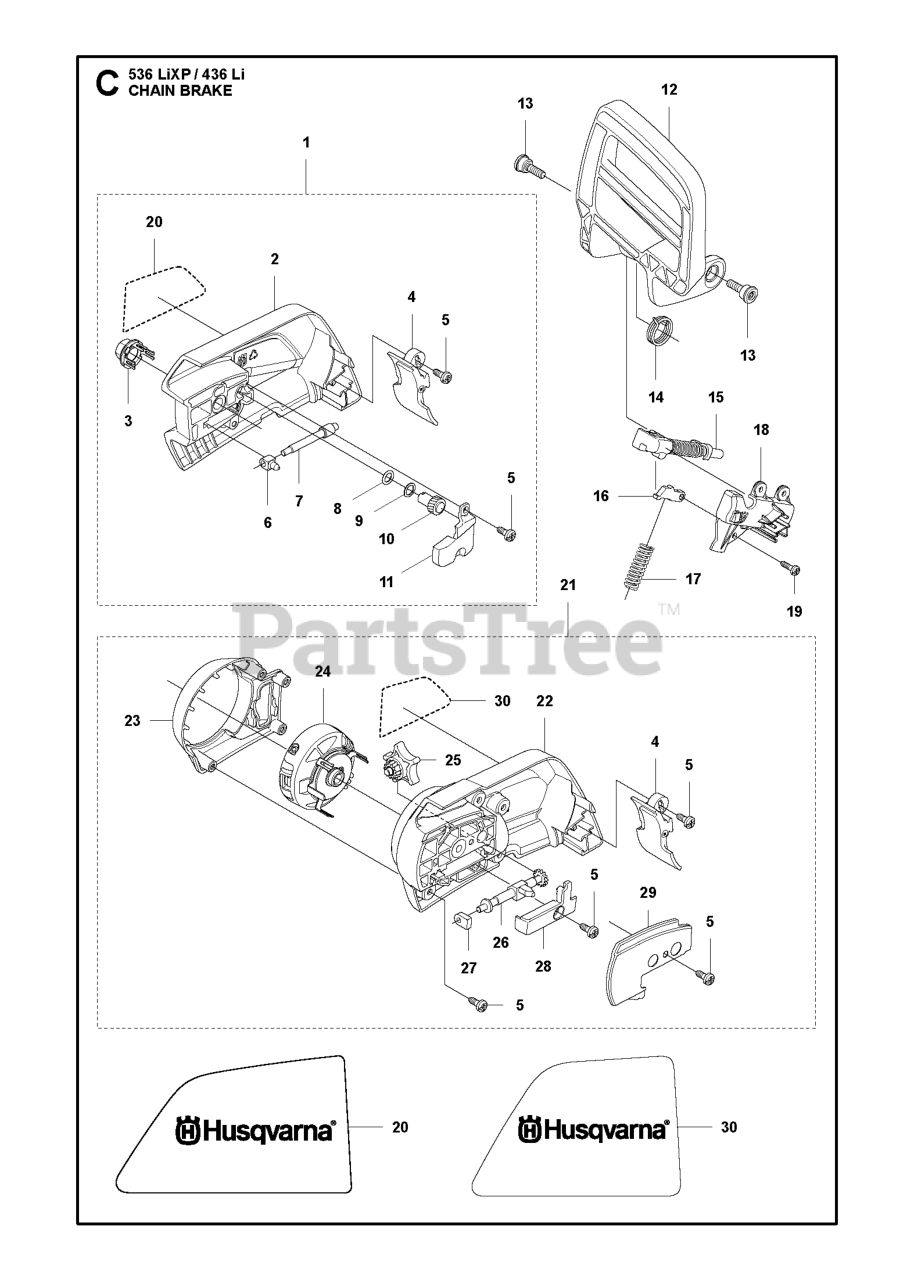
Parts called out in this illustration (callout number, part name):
1	CLUTCH COVER ASSY
2	CLUTCH COVER
3	NUT RETAINER ASSY
4	CHIP GUARD
5	SCREW
6	PAWL
7	SCREW
8	O-RING
9	WASHER
10	WORM WHEEL
11	COVER LID
12	HAND GUARD
14	TORSION SPRING
15	SHAFT ASSY
20	DECAL
21	CLUTCH COVER ASSY LI
22	CLUTCH COVER
23	COVER
24	KNOB UNLOSEABLE
25	CHAIN TENSIONER
26	CHAIN TENSION SCREW COMPL.
27	BEARING SLEEVE
28	COVER
29	WEAR PLATE
30	DECAL
